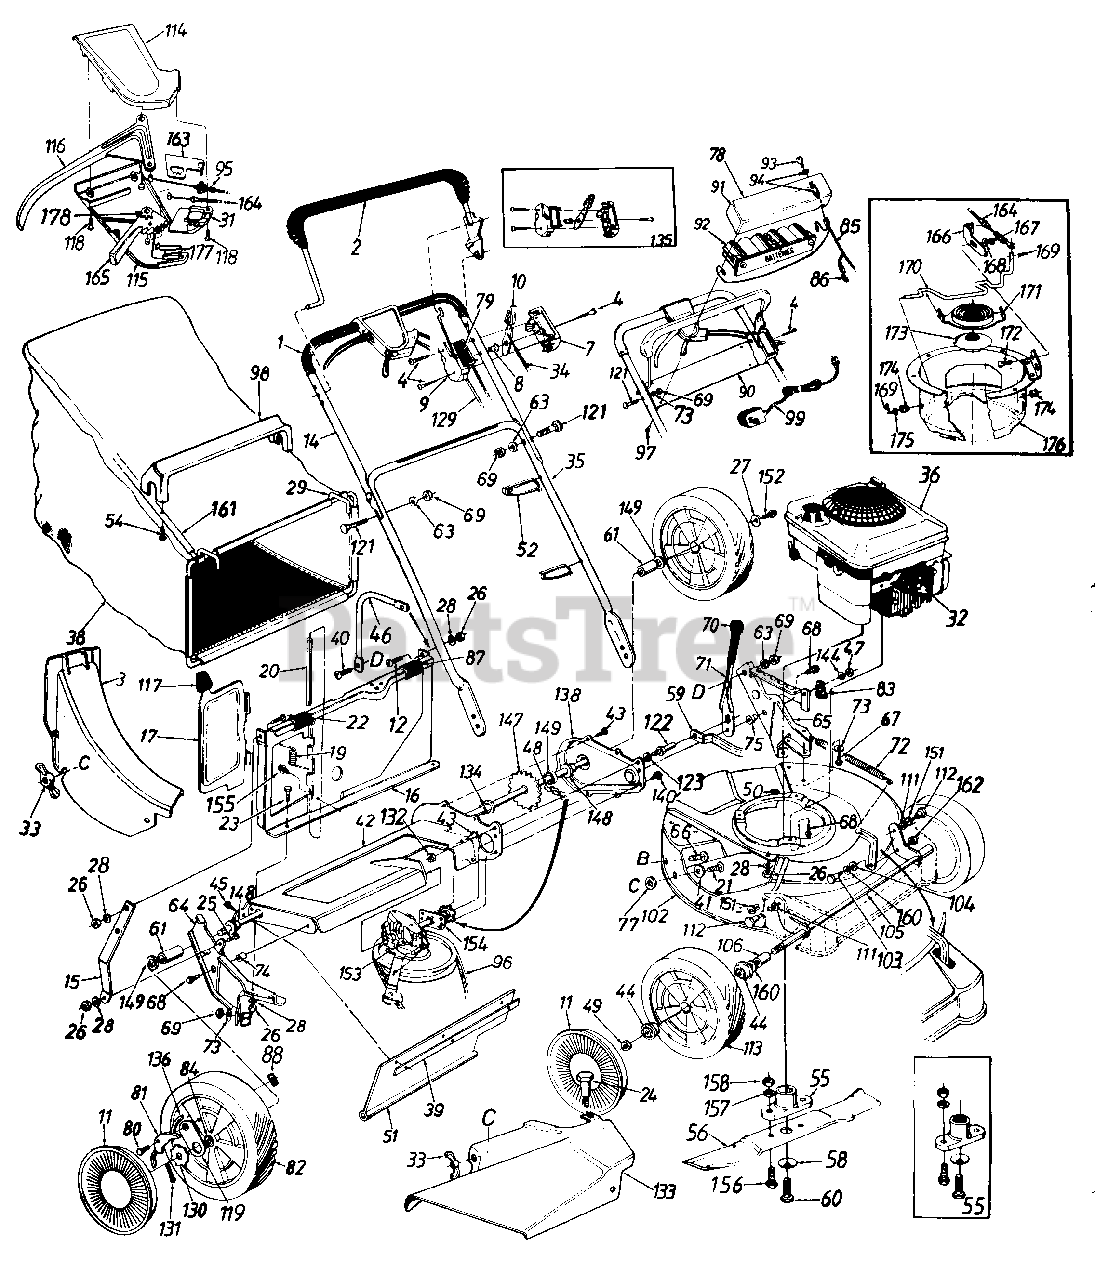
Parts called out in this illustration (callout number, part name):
1	Foam Grip
2	Control Handle Ass'y.-L.H.
3	Rear Discharge Chute Ass'y.
4	Truss Mach. Scr. #12 x 1.50" Lg.
7	Control Panel Half
8	Control Disc Pin
9	Clutch Panel Half
10	Throttle Control Lever
11	Hub Cap
12	Truss Mach. Scr. 1/4-20 x .62" Lg.
14	Upper Handle-Painted
19	Torsion Spring
20	Pivot Pin
21	Carriage Bolt 1/4-20 x .62"*
22	Truss Mach. Scr. 1/4-20 x 3/4" Lg
23	Hex Bolt 1/4-20 x .50" Lg.
24	Shoulder Bolt .312 Dia. x .18 Lg.-Special
25	Hex Bolt 1/4-20 x .62" Lg.
26	Hex Nut 1/4-20 Thd.
27	Bell-Wash. 1/4" I.D.
28	L-Wash. 1/4" I.D.
31	S.P. Control Cover
32	Spark Plug Insulator
33	Wing Nut w/Washer
34	Throttle Control Wire 61"
35	Lower Handle-Painted
36	Engine
38	Grass Bag
39	Retaining Strip
40	Truss Mach. Scr. 5/16-18 x .75" Lg.
41	Fl-Wash. .344" I.D. x .62"
44	Flange Ball Bearing 1/2" I.D.
45	Hex AB-Tap Scr. 1/4 x .6211
46	Catcher Panel Support Arm
47	Hex Patch L-Nut 3/8-24 Thd.
48	#48 Chain .500" Pitch x 30 Links
49	Hex L-Nut 1/2-20 Thd.
51	Rear Flap 3.75" x 17.30" Lg.
52	Cable Tie
54	Hex AB Scr. #12 x 1.25" Lg.
55	Blade Adapter Kit
56	21" Blade
58	Bell-Wash. .46" I.D.
59	Height Adj. Connecting Arm
60	Hex Bolt 7/16-20 x 1.5" Lg. (Grade 5)
61	Spacer .513" I.D. x .703" O.D. x .69" Lg.
63	L-Wash. 5/16" I.D.
64	R.H. Handle Wheel Brkt. Ass'y.
65	L.H. Handle Wheel Brkt. Ass'y.
66	Carriage Bolt 5/16-18 x .62"
67	Hex Wash. Hd. B-Tap Scr. 5/1 6-18
68	Hex Wash. Hd. TT-Tap Scr. 3/8-1 6
69	Hex Nut 5/16-18 Thd.
71	Height Adj. Lever
72	Extension Spring .75" O.D. x8" Lg.
73	Bell-Wash. 5/16" I.D.
74	Spacer
75	Shld. Spacer .500" Dia.
77	Bolt FJetainer 1/4 x .50" O.D.
78	Instruction Label
79	Control Label
80	Shld. Scr. .342" Dia. x .268
81	Pawl
82	Wheel Ass'y. Comp.
83	Clamp
84	Bearing 1/2" I.D.
85	Wire Harness
86	Plug
87	Panel Clip
88	Flat Weld Nut 1/4-20 Thd.
90	Lower Battery Tray
91	Upper Battery Tray
92	12 Volt Battery
93	Key
94	Key Switch
95	S.P. Cable
96	"V"-Belt
97	Hex AB-Tap Scr. 1" Lg.
98	Bag Handle
99	Battery Charger
102	21" Deck Ass'y.
103	Shld. Bolt .5" Dia. x .295
104	Bell-Wash. .515" I.D. x 1.0" O.D.
105	Front Axle Ass'y.
106	Sleeve .526" I.D. x .690" O.D. x .880" Lg.
111	Intern. L-Wash. 3/8 I.D.
112	Shld. Bolt .575" Dia. x .42
113	Wheel Ass'y. Comp.
114	Self-Propelled Control Cover
115	Self-Propelled Control Cover
116	Control Lever
117	Door Grip
118	Fl-"C"-Sunk Hd. Tap Scr. #10 x .75" Lg.
119	Pawl Plate
121	Curved Carr. Bolt 5/16-18 x 1.38" Lg.
122	Shld. Pin 3/8-24 x 1.43" Lg.
123	L-Wash. 3/8" I.D.
129	Control Cable 46" Lg.
130	Ratchet Wheel 1.62" O.D.
131	Cotter Pin 1/8" Dia. x 1.00" Lg.
132	Hex Jam Nut 3/8-24 Thd.
133	Side Chute Deflector Ass'y.
134	Hex Flange Bearing
135	Kit-Control Housing Comp.
136	Spring-Nylon
144	Fl-Wash. .385" I.D. x .37"
147	Rear Shaft Ass'y. 21.94" Lg.
148	Hex Flange Bearing .506" I.D. Plastic
149	Fl-Wash. .531" I.D. x .930"
151	Flanged Nyliner Brg.
152	Hex Bolt 1/4-20 x .62" Lg. (Grade 5)
153	Transmission Comp.
154	Hex Bearing Cup
155	Hex B-Tap Scr. #10 x .38
156	Hex Scr. 3/8-24 x 1.0" Lg.
157	L-Wash. 3/8" I.D.
158	Hex Nut 3/8-24 Thd.
160	Fl-Wash. .51" I.D. x.75" O.D.
162	Hex Jam Nut 318-16 Thd.
163	6-Speed Rack Cable Brkt.
164	Spd. Control Cable-50n Lg.
165	6-Spd. Shift Lever
168	Hex Cent. L-Nut 1/4-20 Thd.
169	Cot-Pin 3/32" Dia. x .75" Lg.
170	Shift Rod
171	Movable Pulley Half Ass'y.
172	Carr. Bolt 1/4-20 x .50" Lg.
173	Spined Pulley Half
174	Flanged Bushing
175	Fl-Wash. .328" I.D. x .68" O.D.
176	Cable Mtg. Brkt. Ass'y.
177	Shift Lever Spring
178	3 Tooth Rack Gear Insert
